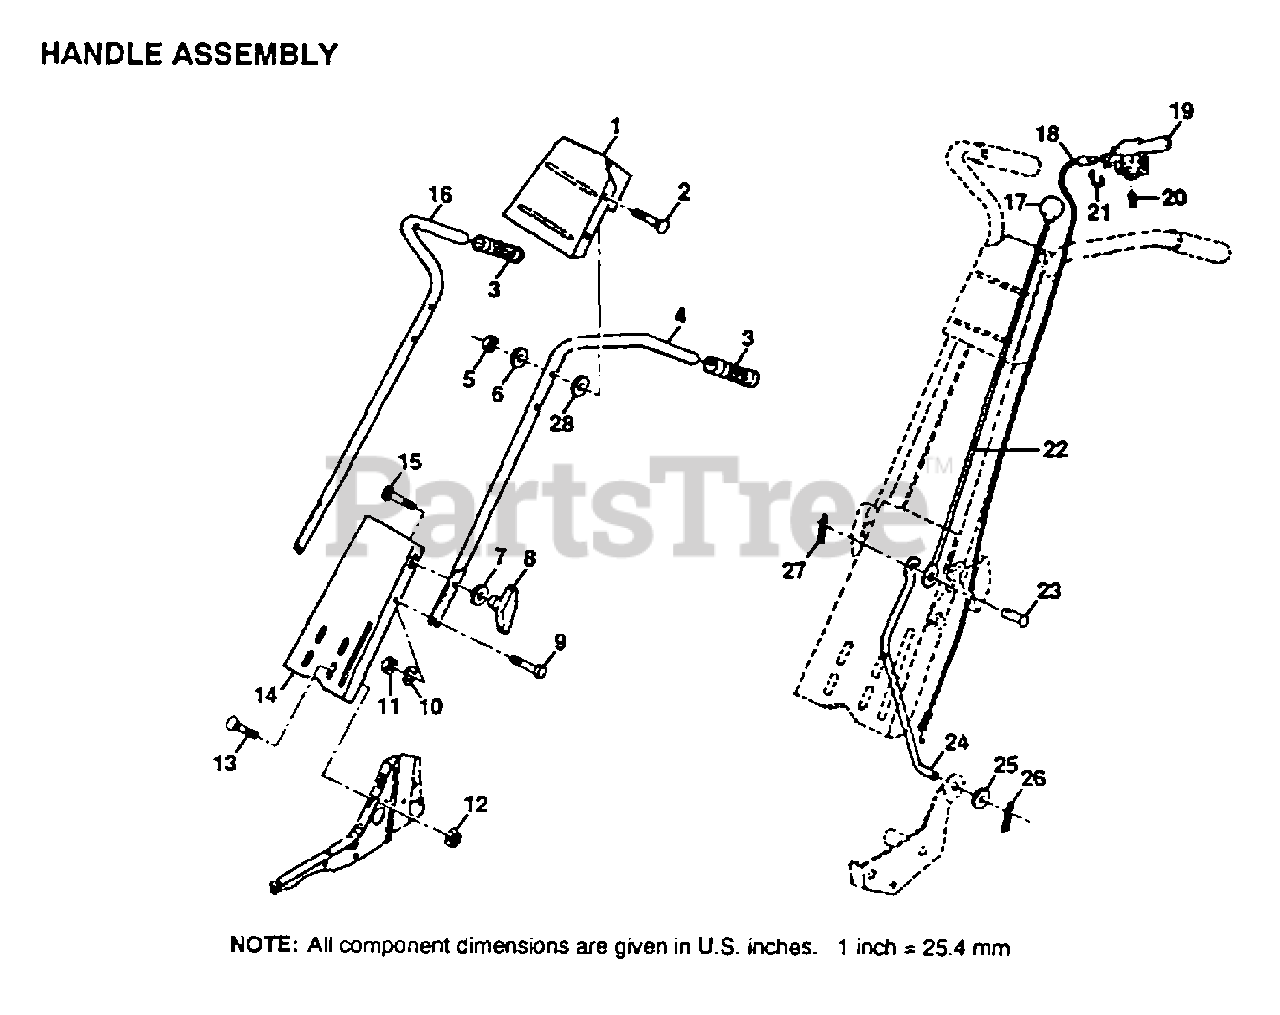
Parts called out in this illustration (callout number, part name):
1	"BRKT, HANDLE"
2	BOLT
6	WASHER
7	WASHER
8	KNOB HANDLE
10	LOCKWASHER
11	NUT.HEX.5/16-18
12	NUT
13	BOLT
14	"PANEL, HANDLE"
15	BOLT
17	KNOB T(3/8 HOLE)
18	CABLE CLUTCH T
19	CONTROL LEVER TI
20	SCREW
21	E-RING
22	ROD REVERSE TI
23	RIVET.RD.HD.DRILL
24	REVERSE ROD TI
25	WASHER
26	COTTER PIN
28	WASHER
